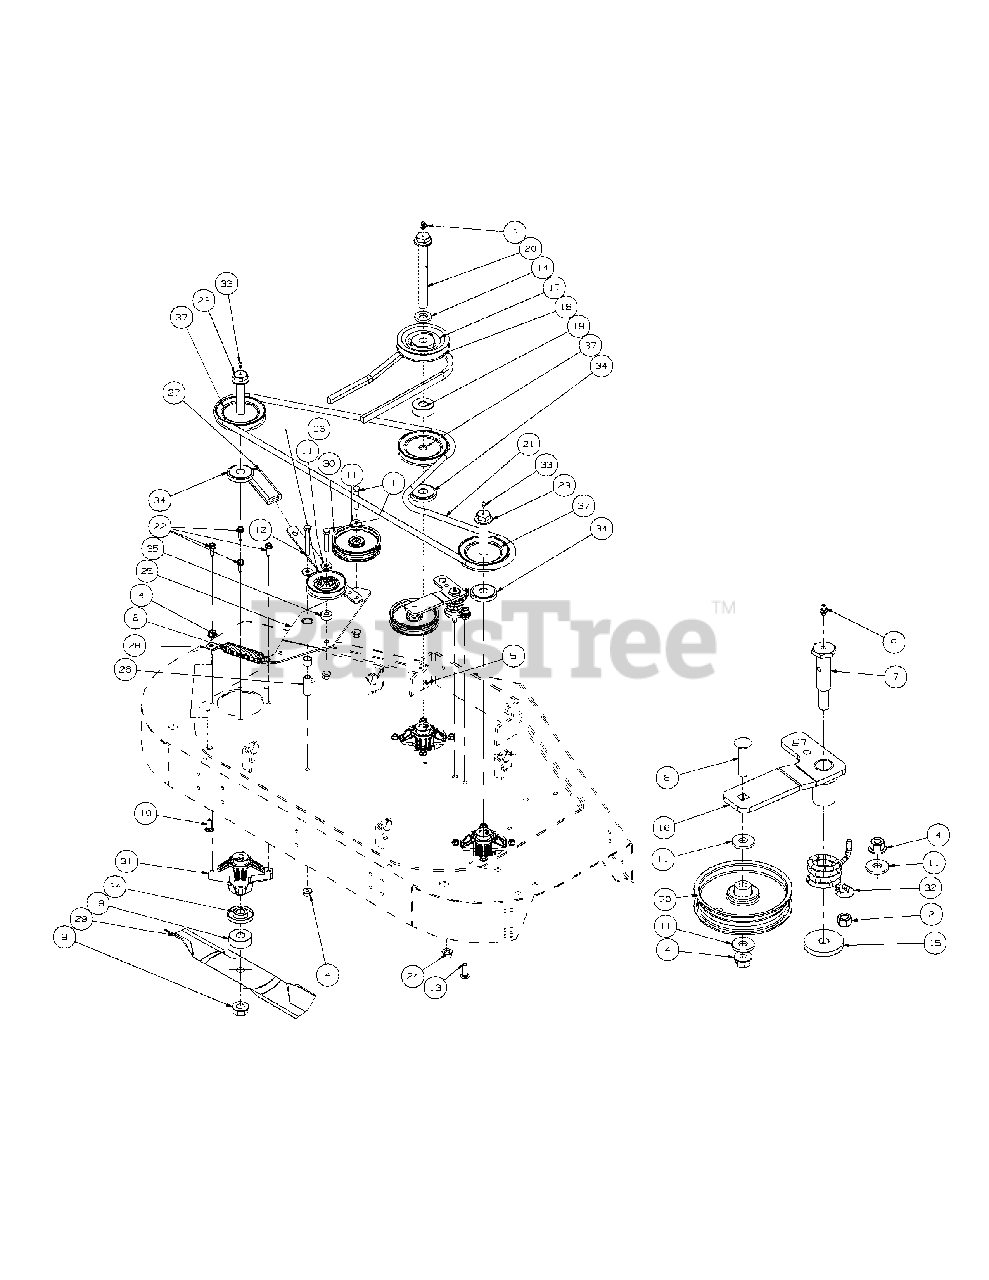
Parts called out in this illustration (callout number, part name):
1	Hex Cap Screw, 3/8-16 x 2.00
2	Hex Nut 3/8-16
3	Grease Fitting, 90°
4	Hex Nut, 3/8-16 Flange Lock
5	Grease Fitting, 1/4-28 x 3/16
6	Extension Spring, 1.0 OD x 5.00
7	Shoulder Screw, 7/16-14
8	Hex Carriage Screw, 3/8-16, 1.75
9	Hex Flange Nut, 3/4-16
10	Carriage Bolt, 3/8-16 x 1.00
11	Flat Washer, .406 ID x 1.0 OD x .105
12	Hex Cap Screw 3/8-16 x 2.75
13	Carraige Screw, 3/8-16 x 1.25
14	Spacer, .812 ID x .218
15	Flat Washer, 7/16 ID x 1.75 OD
16	Idler Arm Assembly, Deck Spindle includes:
17	V-Pulley, 4.75 OD
18	V-Belt, B-Section
19	Spacer .760 ID x 2.00 OD x 0.790
20	Spindle Bolt, 3/4-16 x 7.155
21	V-Belt, A-Section
22	Self Tapping Screw 5/16-18 x 1.00
23	Spindle Bolt 3/4-16 x 5.37
24	Nut, 7/16-20, FlangeLock
25	Idler Arm Assembly, Double, includes:
26	Spacer, .39 ID x .625 OD x 1.875
27	Grip, 1.0 x 3.2 x .25
28	Tension Spring Bracket
29	Blade, 17.0, Hi-Lift, 0.756 ID
30	Flat Pulley
31	Spindle Assembly
32	Idler Torsion Spring
33	Grease Fitting
34	Spindle Spacer
35	Spacer .406 ID x 1.0 OD
36	V-Pulley, 3.5 OD
